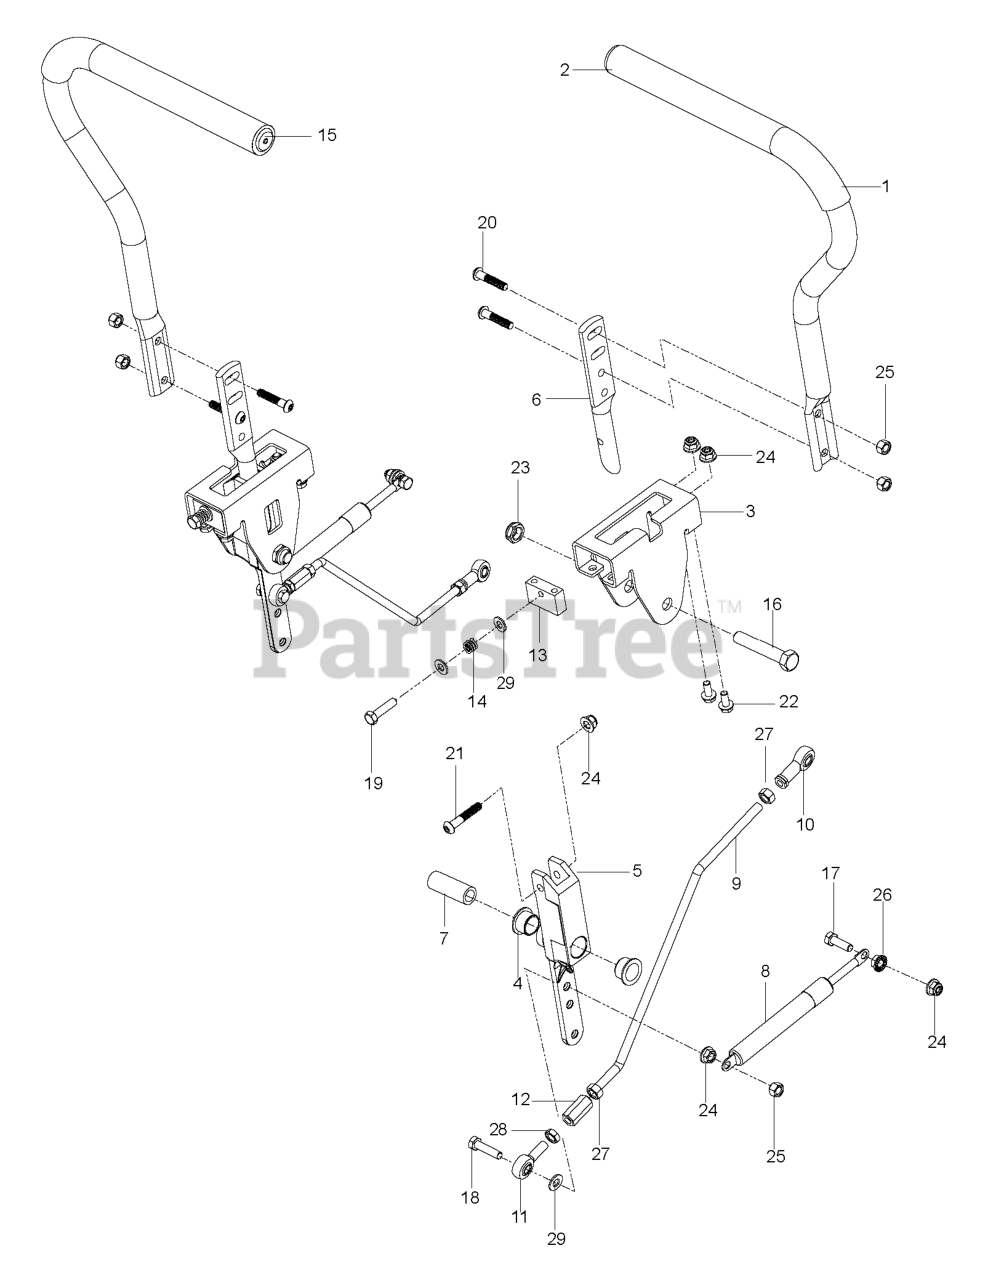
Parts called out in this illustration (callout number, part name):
1	LEVER ASSEMBLY
2	GRIP, FOAM (GROUND) 15
3	BRACKET, CONTROL
4	BEARING, FLANGE
5	LEVER CONTROL PIVOT
6	LEVER.HANDLE MOUNT
7	SPACER, PIVOT CONTROL
9	ROD, MOTION CONTROL
10	RH ROD END
11	RP.ROD.END.LH
12	HCS 1/2C X 2 3/4
12	ROD END COUPLER
13	BLOCK.TRACKING
15	END PLUG 15/16 (BLACK)
16	HCS 1/2C X 2 3/4
17	HCS 5/16C X 1
18	HCS 5/16-18X1-3/4 TPBLT
19	CAPSCREW 5/16 X 1/1/2 HEX HEAD
20	SCREW 5/16-18 X 1 BTN-HD
21	SCREW 5/16-18 X 1 3/4 BTN-HD
22	HHFS 5/16-18 X 3/4
23	NUT 1/2-13 HEX JM NYL
24	5/16-18 NYLOC FLANGE NUT
25	NUT 5/16 NYLOC
26	NUT 5/16C WHIZ
28	NUT 5/16F LEFTHAND
29	FLAT WASHER 5/16 SAE
